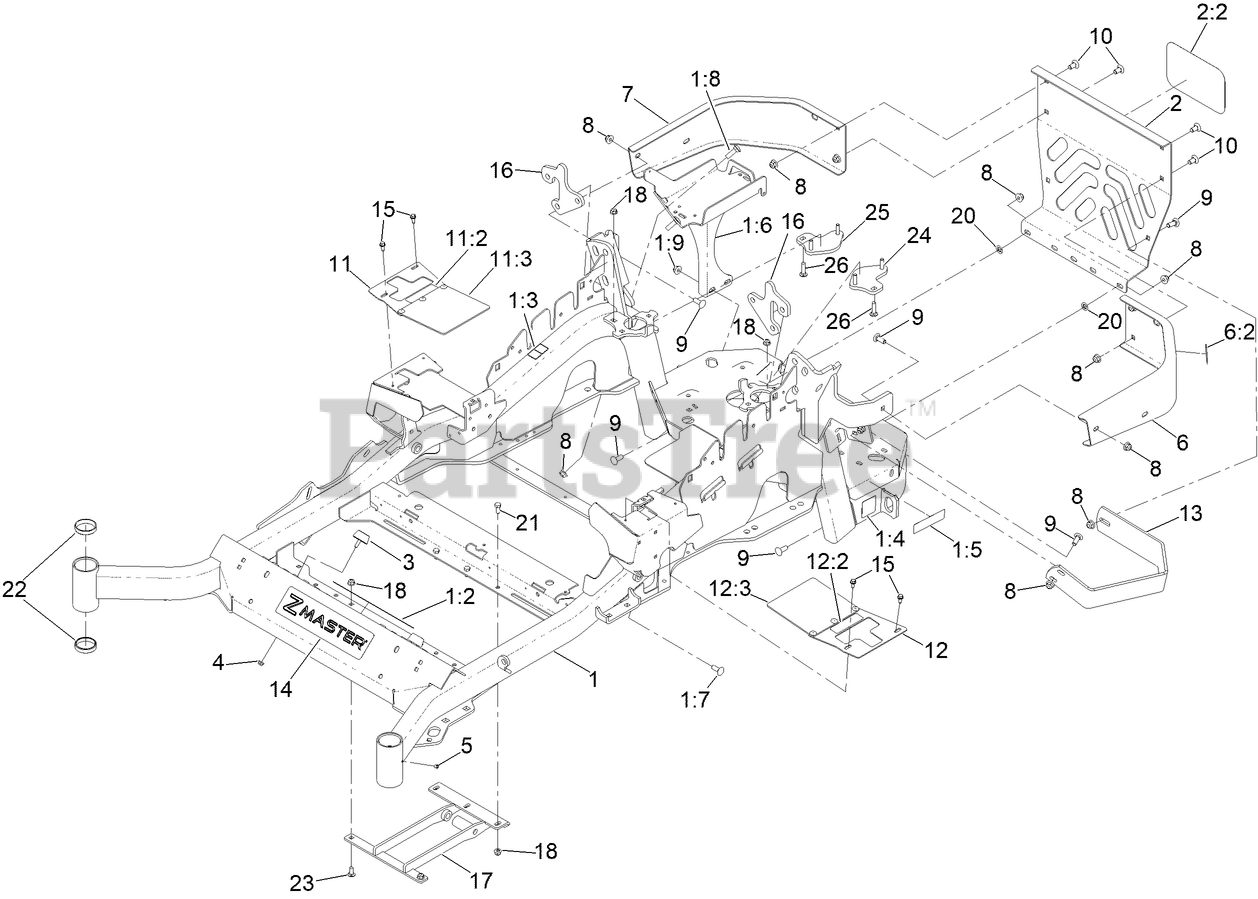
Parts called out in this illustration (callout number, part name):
1	MAINFRAME SERVICE ASM - 60
1:2	DECAL-DANGER
1:3	DECAL-WARNING
1:4	DECAL-HAZARD, PINCHED FINGER
1:5	DECAL-ARRESTOR, SPARK
1:6	BATTERY MOUNT ASM
1:7	SCREW-CARR
1:8	BOLT-CARR
1:9	NUT-HF, NI
2	REAR GUARD ASM
2:2	DECAL
3	BUMPER
4	NUT-HF
6	LH BUMPER ASM
6:2	DECAL-WARNING
7	BUMPER-RH
8	NUT-HF, NI
9	SCREW-CARR
10	SCREW-CARR
11	RH MOTION CONTROL COVER ASM
11:2	DECAL-CONTROL, MOTION
11:3	FLAP-RUBBER
12	LH MOTION CONTROL COVER ASM
12:2	DECAL-CONTROL, MOTION
12:3	FLAP-RUBBER
13	GUARD-MUFFLER
14	DECAL-CONSOLE
15	SCREW-HWH
16	PLATE-MOUNT, SHOCK
17	MOUNT-LOWER
18	NUT-HF, NI
20	NUT-PUSH
21	SCREW-HH
22	CUP-BEARING
23	SCREW-CARR
24	LH PLATE ASM (W/STUDS)
25	RH PLATE ASM (W/STUDS)
26	SCREW-CARR
